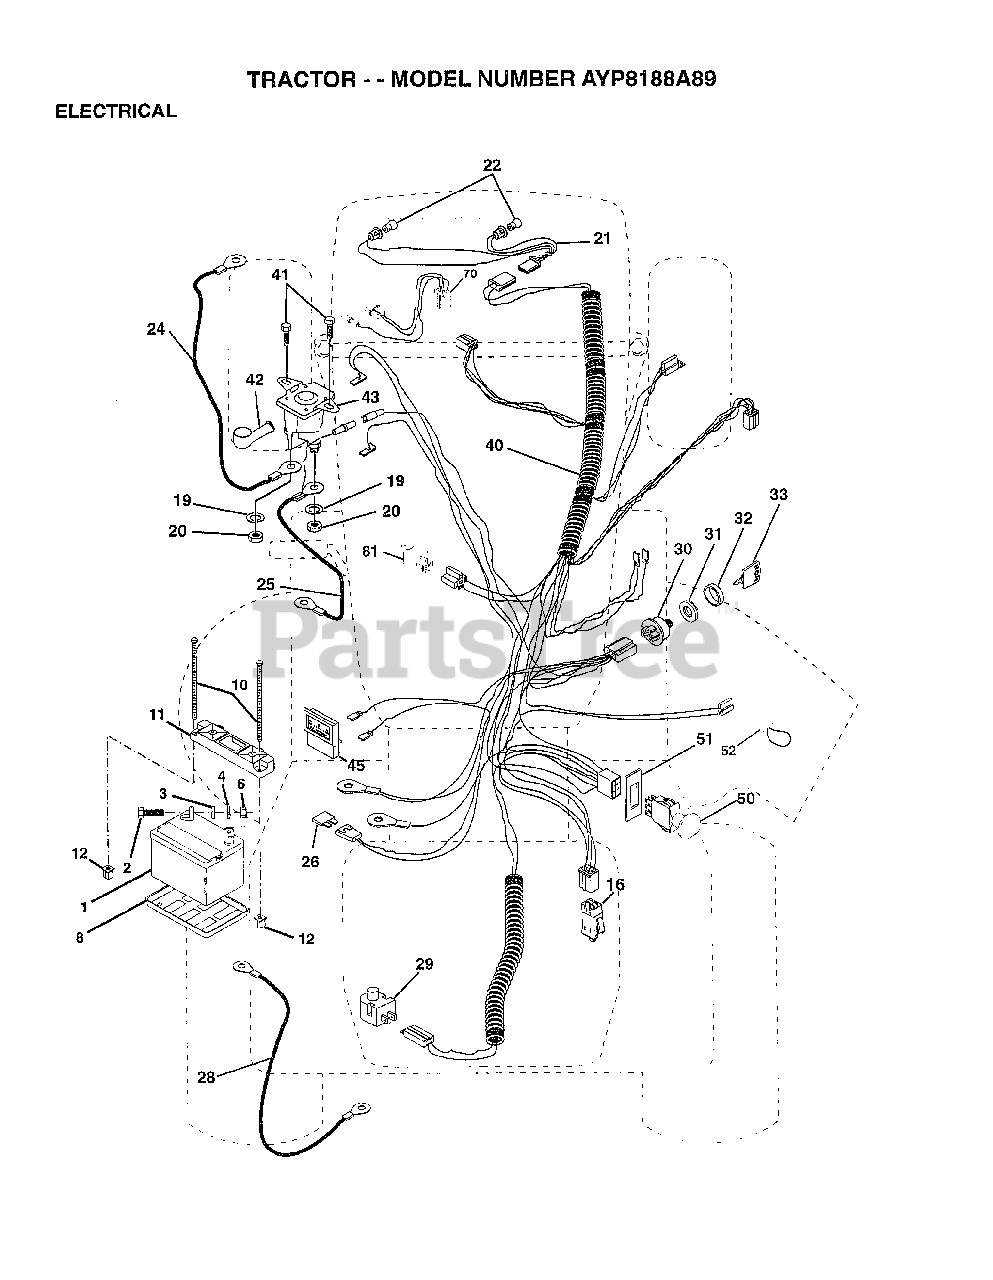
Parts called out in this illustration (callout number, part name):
3	WASHER
4	LOCKWASHER
8	"TRAY T, BATTERY"
11	HOLDDOWN BATTERY
16	SWITCH INTERLOCK
20	NUT
21	"HARNESS,LIGHT SOC"
22	HEADLAMP BULB
24	CABLE-BATTERY T
25	CABLE.6GA.12.5.
26	FUSE HYT
28	CABLE T
29	SWITCH.PLUNGER
30	SWITCH IGN 4POS
31	NUT IGNITION
32	COVER KEY SWITCH
33	KEY
40	HARNESS.IGNITON
41	SCREW
45	AMMETER
50	PTO SWITCH.BLK
51	RING RETAIN PTO
52	PROTECTION LOOP
70	HARNESS.ENG.B&S
81	RELAY ASSY T
